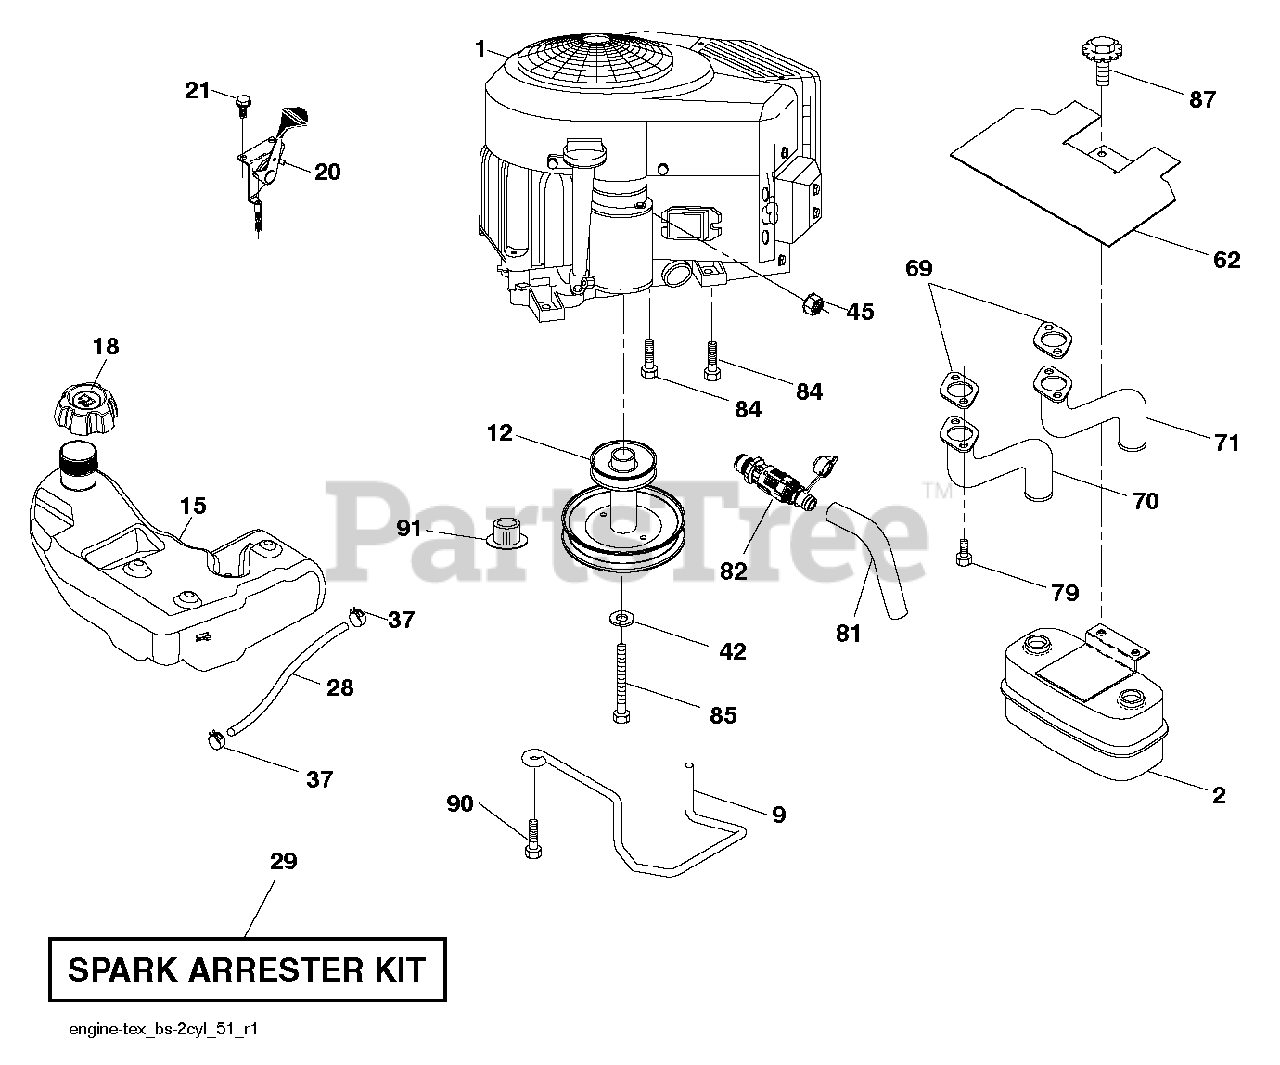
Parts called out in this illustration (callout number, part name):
2	MUFFLER.TWIN.CYL.LOW.TONE
9	KEEPER.BELT.ENGINE.4.2
12	PULLY ENGINE
15	TANK.ASSY.3.GAL.EPA
18	CAP ASM.FL.RTCHT.3"GRY.E10
20	CONTROL.TH/CK.COBRA.B&S.TWN.
21	SCREW.#10 X 0.750.BOS THREAD
29	ARRESTER SPARK (OPTIONAL)
37	HOSE CLAMP
42	LOCKWASHER
45	NUT
62	SHIELD.HEAT.MUFFLER
69	GASKET.MUFFLER
70	TUBE MANIFOLD LH
71	EXHAUST TUBE RH
79	SCREW.SOCKET.HEAD.5/16-18
81	TUBE, DRAIN OIL ASM.
82	VALUE.OIL.DRAIN
84	SCREW.3/8-16
85	BOLT HEX 7/16-20X4-1/4"
87	BOLT, 5/16-18 X 1 3/4
90	SCREW 3/8-16X1
91	BUSHING.1.375OD
